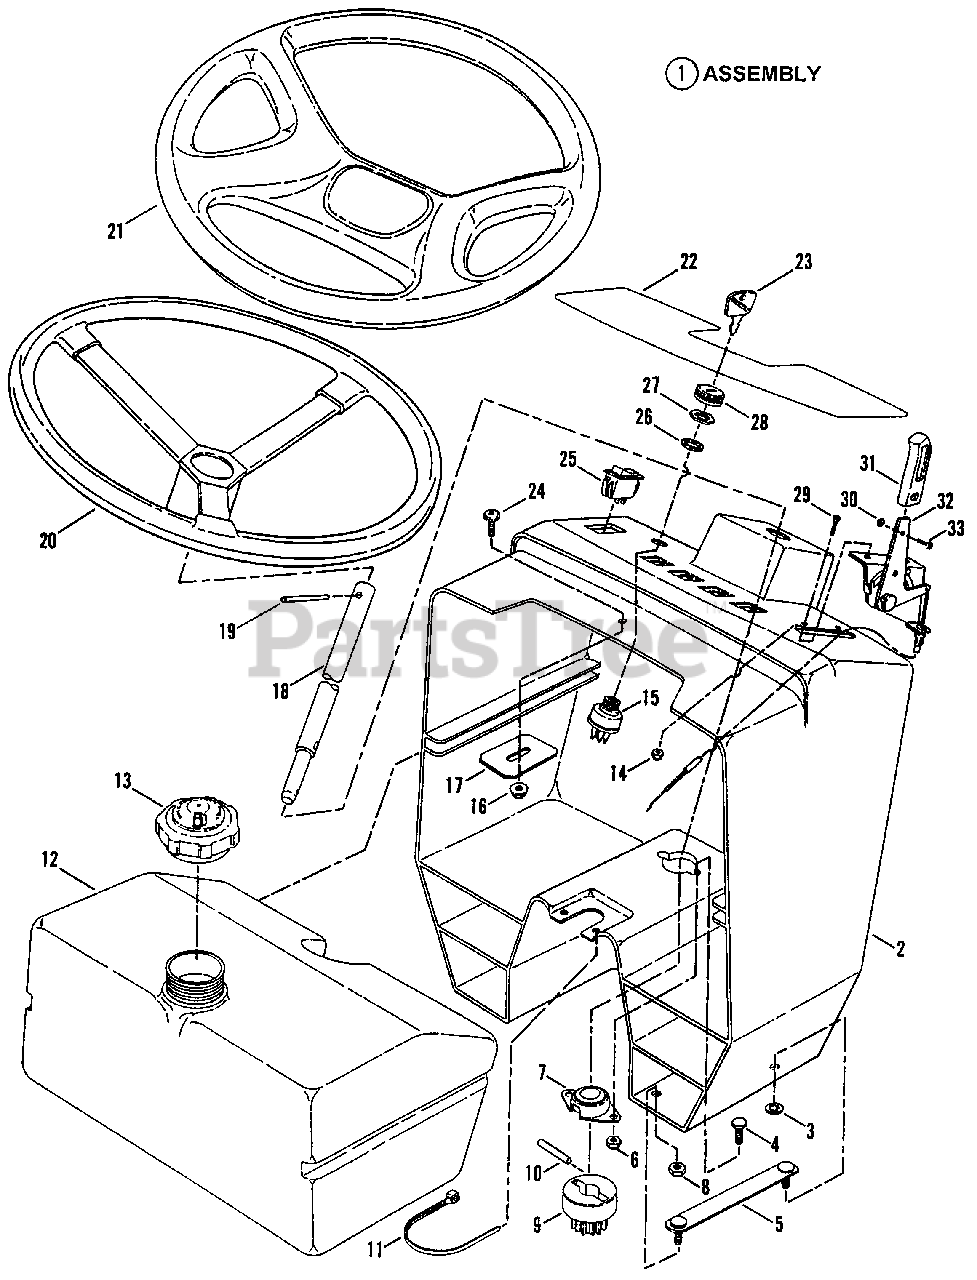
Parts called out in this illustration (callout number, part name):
1	ASSEMBLY, Console
2	CONSOLE
3	RETAINER
4	SCREW, 1/4-20 x 3/4" Hex Head Cap, Grade 5
5	ASSEMBLY, Strap-Clinch Stud
6	NUT, 1/4-20 Hex Nyloc
7	ASSEMBLY, Flange Bearing
8	NUT, 5/16-18 Hex Center Lock
9	GEAR, Pinion, Steering Shaft
10	PIN, Dowel, 1/4 x 1-1/4"
11	TIE, Wire
12	ASSEMBLY, Fuel Tank
13	CAP, Fuel Tank
14	NUT, #10-24 Hex Nyloc
15	KEYSWITCH
16	NUT, 5/16-18 Hex Flange Lock
17	BRACKET, Hood Latch Catch
18	SHAFT, Steering
19	ROLL-PIN
20	STEERING WHEEL
21	STEERING WHEEL
22	DECAL, Console
23	KEY, Switch (With Cover)
24	SCREW, 5/16-18 x 5/8" Truss Head, Torx
25	SWITCH, Lights
27	NUT, 5/8-32 Hex
28	BEZEL
29	SCREW, #10-24 x 5/8" Machine
30	NUT, #8-32 Hex
31	HANDLE, Throttle Control
32	CONTROL, Throttle
33	SCREW, #8-32 x 3/8" Cross-Recessed, Fillester Head
